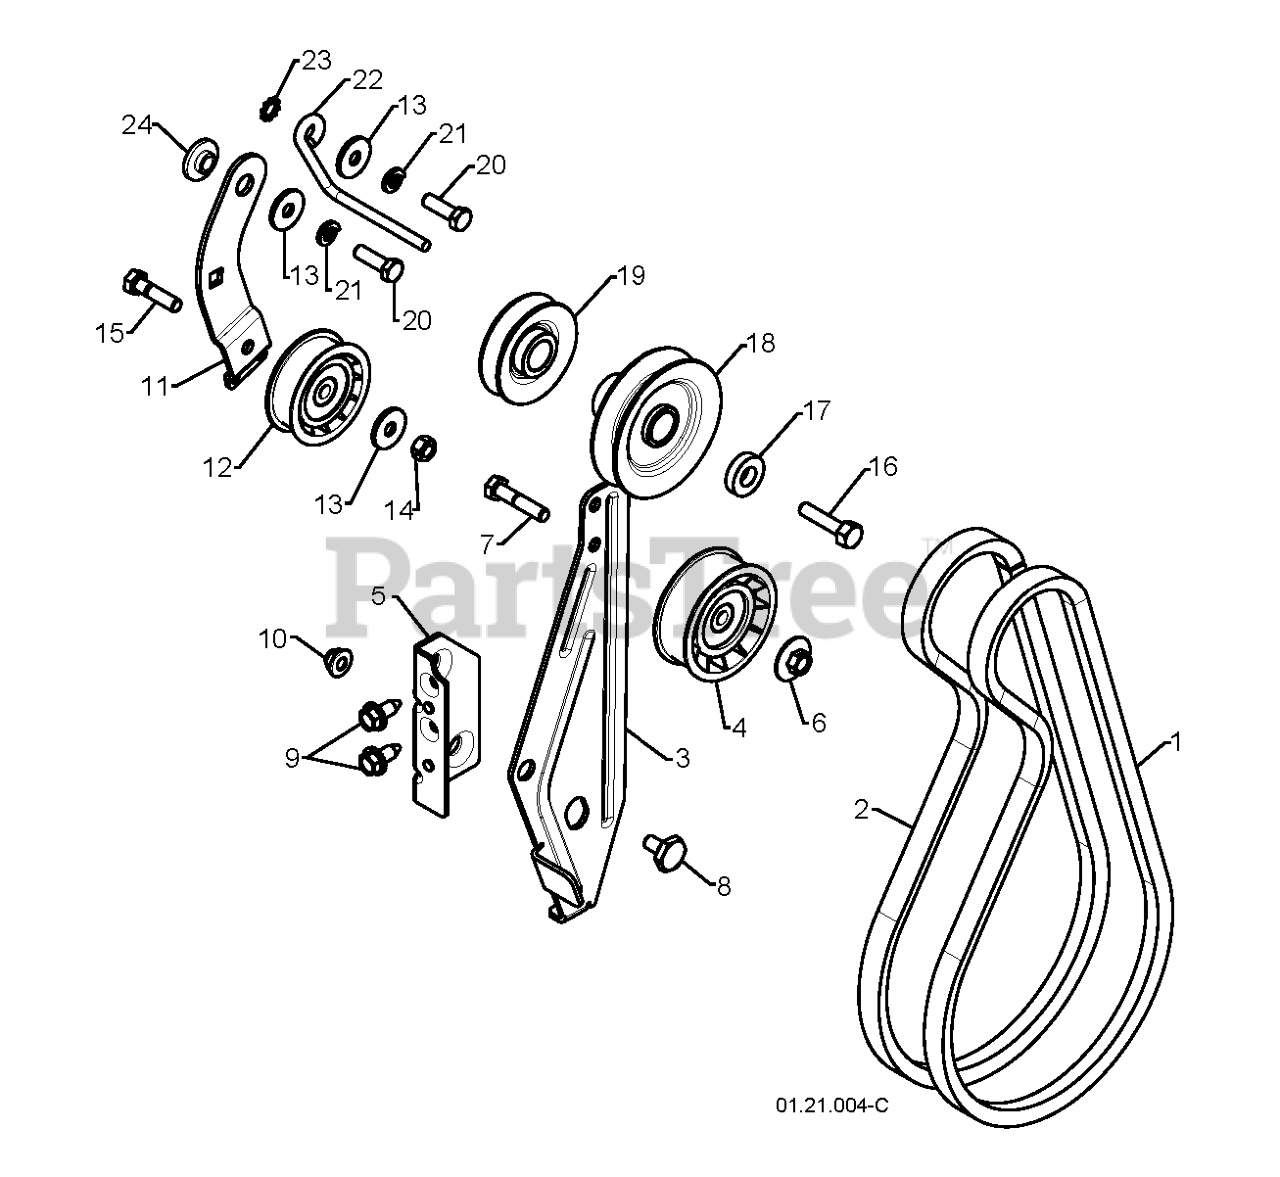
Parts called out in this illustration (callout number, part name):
1	VBELT; IMPELLER_39.09
2	V-BELT TRACTION 34.25
3	ARM.IDLER.BRAKE.
4	PULLEY.IDLER.W/SPACER.
5	RP BRACKET.IDLER.PIVOT
6	NUT.FLANGE.HEX.5/16X18.BLACK
7	HEX BOLT
8	BOLT.SHOULDER.1/2X12
9	BOLT.HEX.HD.WASHER.5/16-18X.75
10	NUTNYLOK.FLRANGE.5/16-18
11	ARM, IDLER
12	PULLEY.W/SPACER.2.25
13	STEEL WASHER
14	NUT.71038.31-18.HEX.NYLOCK
15	BOLT.5/16-18X1-1/4 FULL.THREAD
16	SCREW, HEX HD 3/8-24 X 1-3/8
17	WASHER, FLAT 3/8
18	PULLEY.ENG.IMPELLER.SNOW
19	PULLEY.ENG.TRACTION
21	WASHER.LOCK.HVY.HLCL.SPR.5/16
22	BELT.GUIDE.RH
23	WASHER EXT TOOTH LOCK 5/16
24	RP BUSHING, IDLER PIVOT
